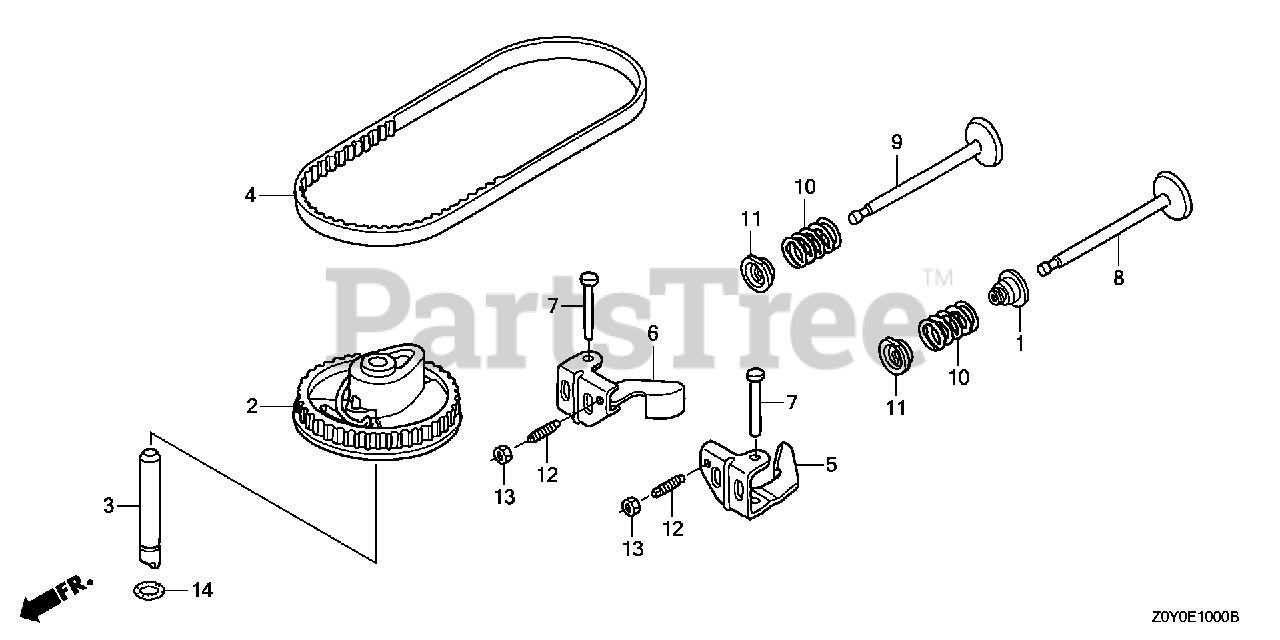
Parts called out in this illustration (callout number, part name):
1	SEAL, VALVE STEM
2	PULLEY, CAMSHAFT
3	SHAFT, CAM PULLEY
4	BELT, TIMING (84HU7 G-200)
5	ARM, IN. VALVE ROCKER
6	ARM, EX. VALVE ROCKER
7	SHAFT, ROCKER ARM
8	VALVE, IN. (TECHNOSTAR)
8	VALVE, IN.
9	VALVE, EX. (L8E)
10	SPRING, VALVE
11	RETAINER, IN. VALVE SPRING
11	RETAINER, VALVE SPRING
11	RETAINER, VALVE SPRING (EXHAUST SIDE)
12	SCREW, TAPPET ADJ.
13	NUT, TAPPET ADJ.
14	O-RING (6.8X1.9) (ARAI)
